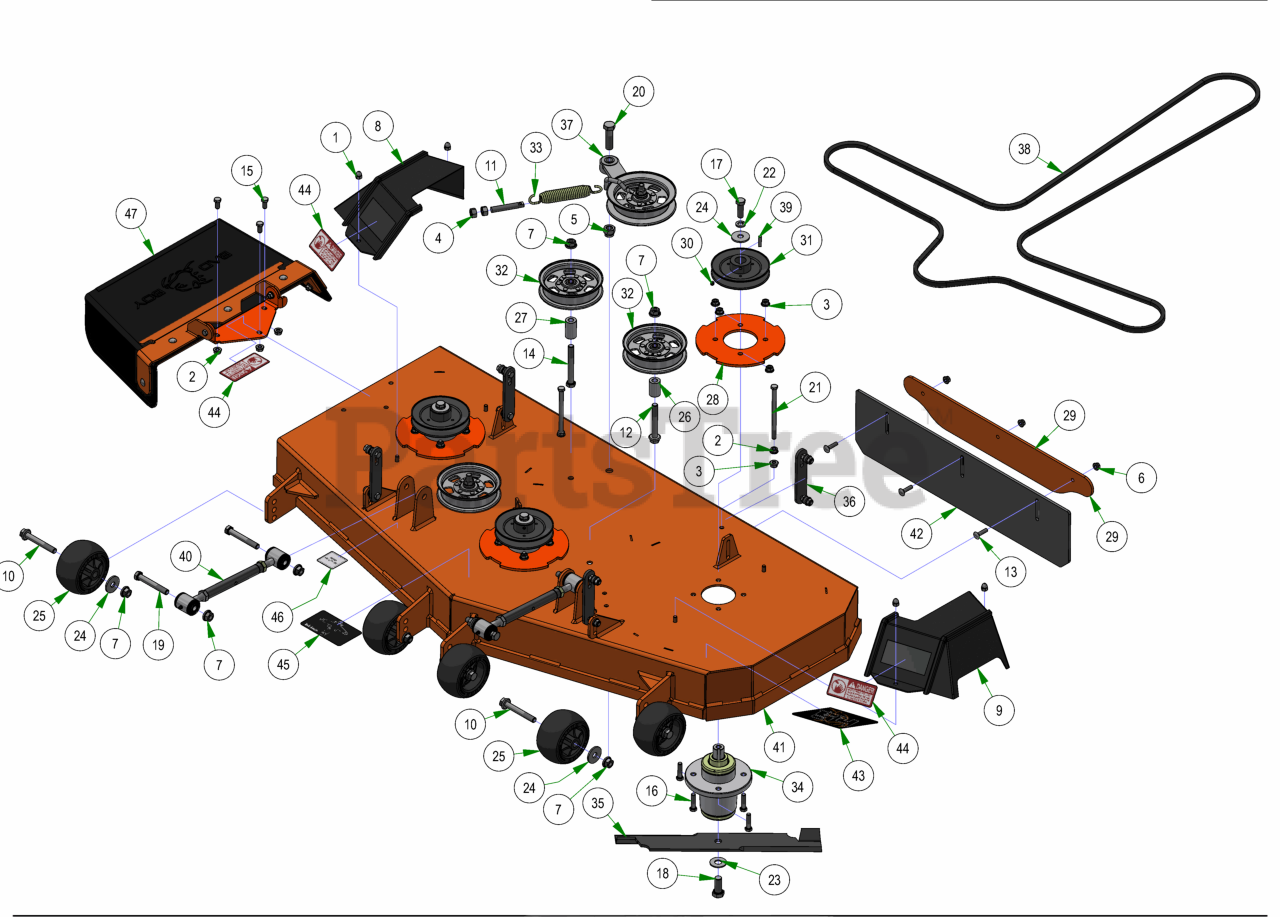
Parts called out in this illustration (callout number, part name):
1	5/16-18 ACORN NUT HIGH-CROWN ZC
2	3/8-16 HEX SERRATED FLANGE NUT HARD/ZINC
3	3/8-16 NYLON INSERT FLANGE LOCKNUT (GR.F) ZINC
4	1/2-13 HEX NUT ZINC
5	5/8-11 NYLON INSERT LOCKNUT ZINC
6	5/16-18 NYLON INSERT FLANGE LOCKNUT ZINC
7	1/2-13 NYLON INSERT FLANGE LOCKNUT ZINC
8	2021 Maverick 54”/60” RH Pulley Cover
9	2021 Maverick 54”/60” LH Pulley Cover
10	1/2-13 X 90MM HEX FLANGE BOLT W/SHOULDER (GR.8) ZINC
11	All Thread
12	1/2-13 X 3-1/2 HEX FLANGE BOLT (GR.8) ZINC
13	5/16-18 X 1-1/4 CARRIAGE BOLT ZINC
14	1/2-13 X 4 HEX CAP SCREW (GR.8) ZINC YELLOW
15	3/8-16 X 3/4 HEX CAP SCREW (GR.5) ZINC
16	3/8-16 X 1-1/2 HEX CAP SCREW (GR.5) ZINC
17	1/2-20 X 1-1/2 HEX CAP SCREW (GR.5) ZINC
18	5/8-18 X 1-1/2 HEX CAP SCREW (GR.8) ZINC YELLOW
19	1/2-13 X 3-1/2 HEX CAP SCREW (GR.5) ZINC
20	5/8-11 X 2-1/4 HEX CAP SCREW (GR.5) ZINC
21	3/8-16 X 5-1/2 HEX CAP SCREW (GR.5) ZINC
22	1/2 SPLIT LOCKWASHER (GR.8) ZINC/YELLOW
23	5/8 USS FLAT WASHER (1-3/4" OD) GR.8 ZINC YELLOW
24	1/2 BELLEVILLE WASHER (1-5/8 OD X .140 THK) ZINC
25	Deck Wheel
26	.502 ID X .750 OD X 1.500 Long Spacer
27	1 3/4" Pulley Spacer
28	Deck Spindle Support Plate
29	2023 4" & 5" Stripping Kit Plate
30	5/16-24 X 1/4 SOCKET SET SCREW (CUP PT) PLAIN
31	5.25" Deck Spindle Pulley
32	5-3/4 Idler Pulley
33	Deck Idler Spring
34	OUTLAW SPINDLE ASSEMBLY
35	54" Fusion Blade for Avenger/ZT/Mav/Outlaw/Revolt
36	Deck Hanger Assembly
37	Maverick HD & Down Deck Idler Assembly
38	B155.75 Deck Belt
39	1/4 X 1 SQ MACHINERY KEY 1018 STL PLN
40	2018 Maverick Turnbuckle (Top Link)
41	2025 54" x 5" Deck
42	2023 ZT Stripping Kit Rubber
43	54" Grip Deck Decal
44	Danger Decal-Spindle/Discharge
45	Deck Belt Route Decal
46	Deck Impact Patent Decal 9591803
47	Discharge Chute Assembly
